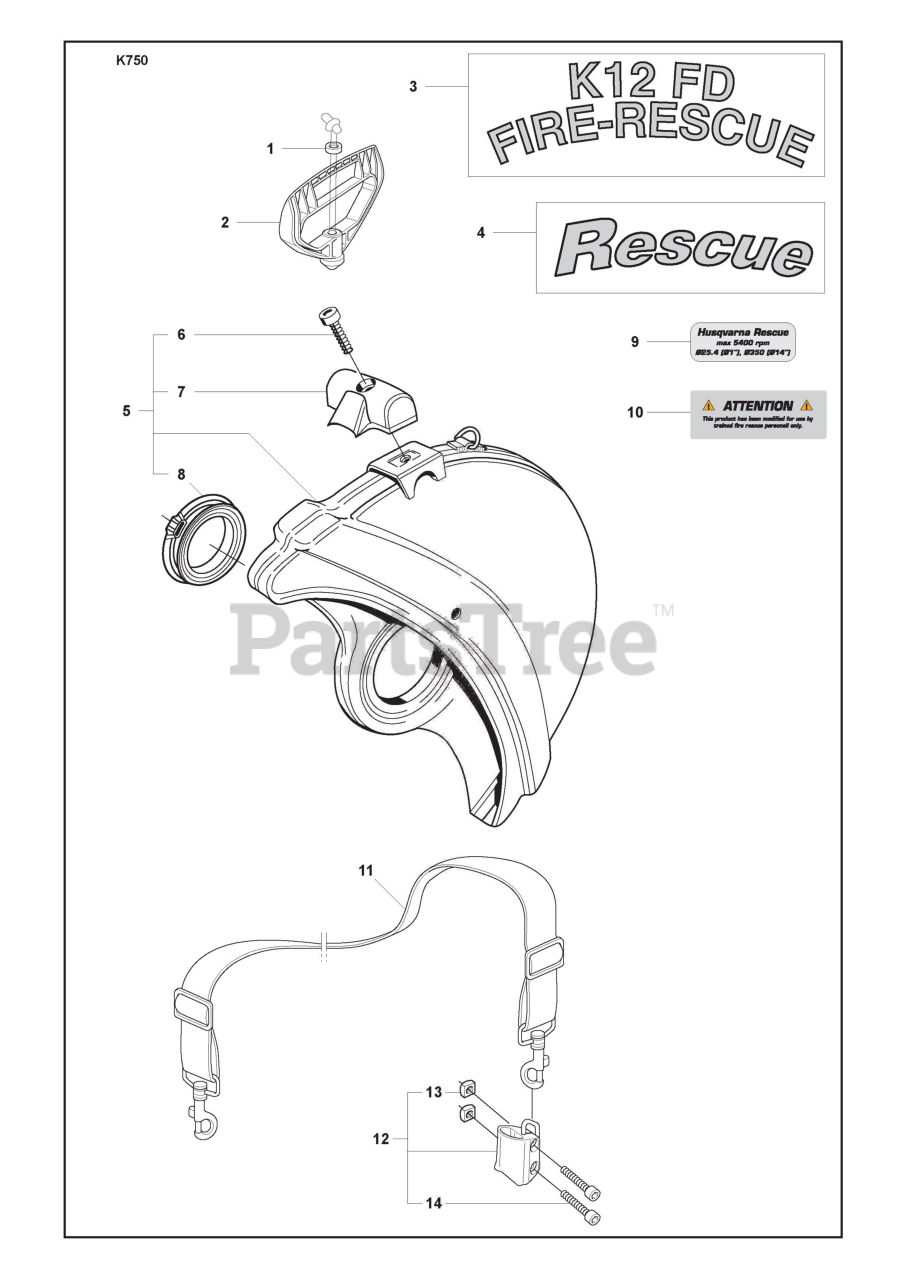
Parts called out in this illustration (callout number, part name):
2	STARTER HANDLE
5	WHEEL GUARD ASSY
6	SCREW
11	SHOULDER STRAP
12	BRACKET
